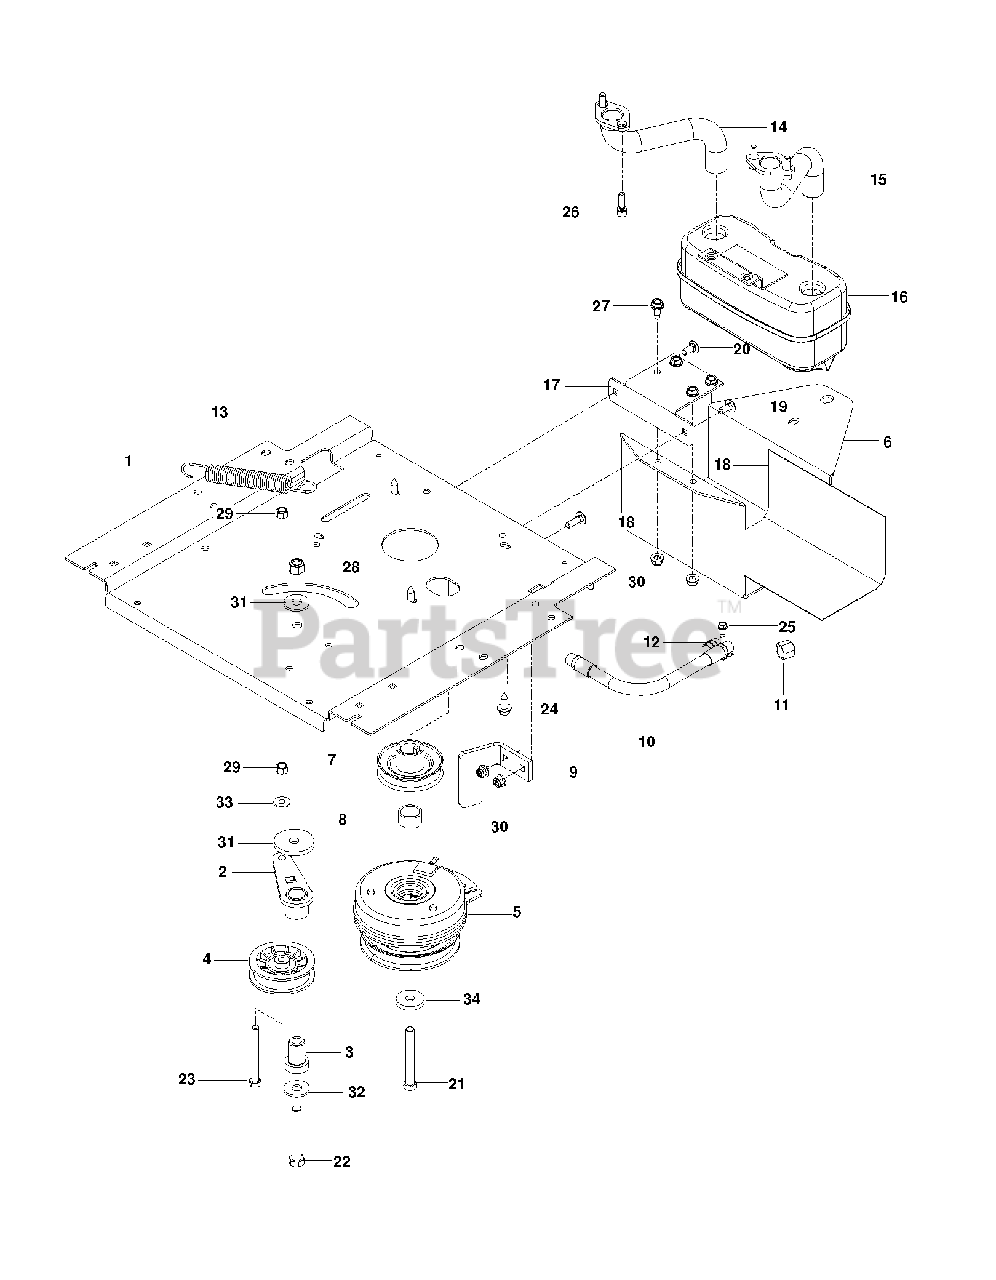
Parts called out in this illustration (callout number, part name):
1	PLATE, ENGINE BLK
2	IDLER ARM WELDMENT
3	IDLER SPINDLE
4	PULLEY, IDLER RAKE & ZTR
5	CLUTCH, 105 FT-LBS
6	GUARD, MUFFLER, BLACK
7	RP PULLEY, ENGINE
8	T & B SPACER
9	STOP, CLUTCH, BLACK
10	OIL DRAIN HOSE
13	SPRING, DECK DRIVE
14	RP.PIPE-EXHAUST LH
15	RP.PIPE-EXHAUST RH
16	MUFFLER ASM TWIN
17	BRACKET, MUFFLER, BLACK
18	HEAT SHIELD
19	RHSNB 5/16C X 1
20	BOLT 5/16C X 3/4" CARRIAGE
21	HCS 7/16-20X3-1/2 GR 5 ZN
22	HCS 1/2C X 3 1/4
23	HCS 3/8-16X3 1/2 GR5
24	HHFS 3/8-16 X 1.0 THD FORMING
25	SCREW 1/4 X 5/8
26	SCREW.SOCKET.HEAD.5/16-18
27	BOLT 5/16-18 X 3/4
28	RP NUT 1/2-13 HEX NYLOC ZD
29	NUT 3/8-16 NYLOC
30	5/16-18 NYLOC FLANGE NUT
31	HEAVY WASHER
32	WASH USS FLAT 1/2
33	WASHER 5/16 FLAT
34	CLUTCH, WASHER
